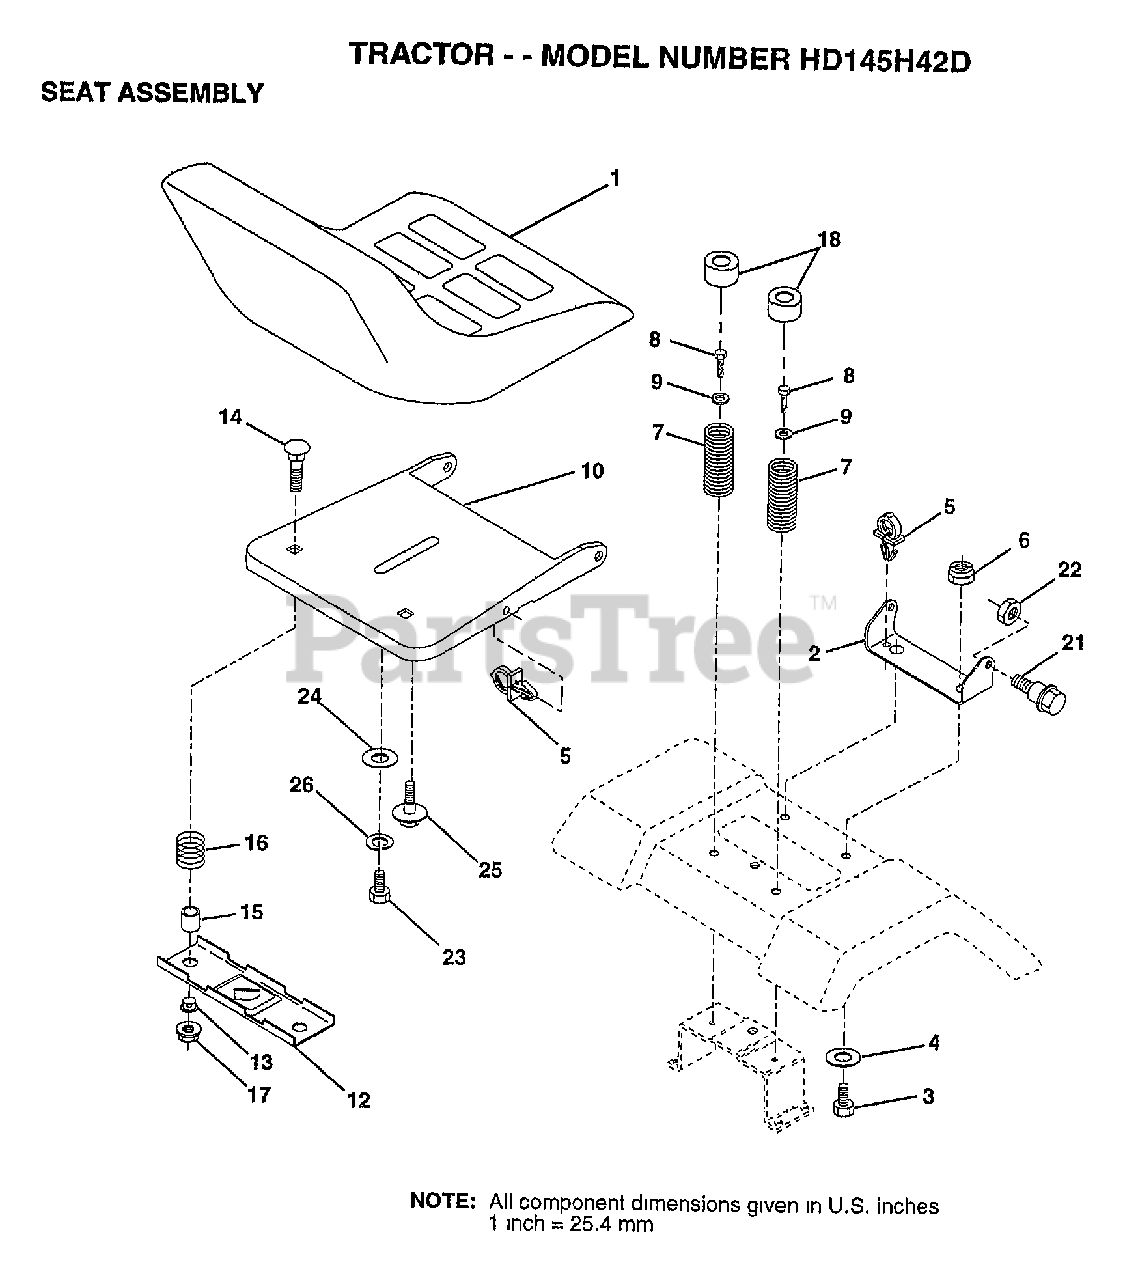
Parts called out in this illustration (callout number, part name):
1	"DECAL-SADDLE,INST"
1	VALVE CAP
2	"DECAL WHEEL,STEER"
2	VALVE STEM LT
3	"DECAL-HOOD,RH"
4	"DECAL-HOOD,LH"
4	TUBE.5.3/4.5/6
5	"DECAL FENDER,SD"
5	"RIM ASM 6"" FRT"
6	FITTING LT
7	"DECAL FENDER,LOGO"
7	"FLANGE, BEARING"
8	"DECAL FENDER,DANG"
8	"RIM AS 8"" REAR"
9	DECAL CLUT/BRAKE
10	TUBE.18X9.5-8
11	DECAL
11	HUB CAP
17	DECAL.BATRY.3-3908
18	"DECAL SEAT,ACC"
19	"DECAL REPLCMT,ENG"
